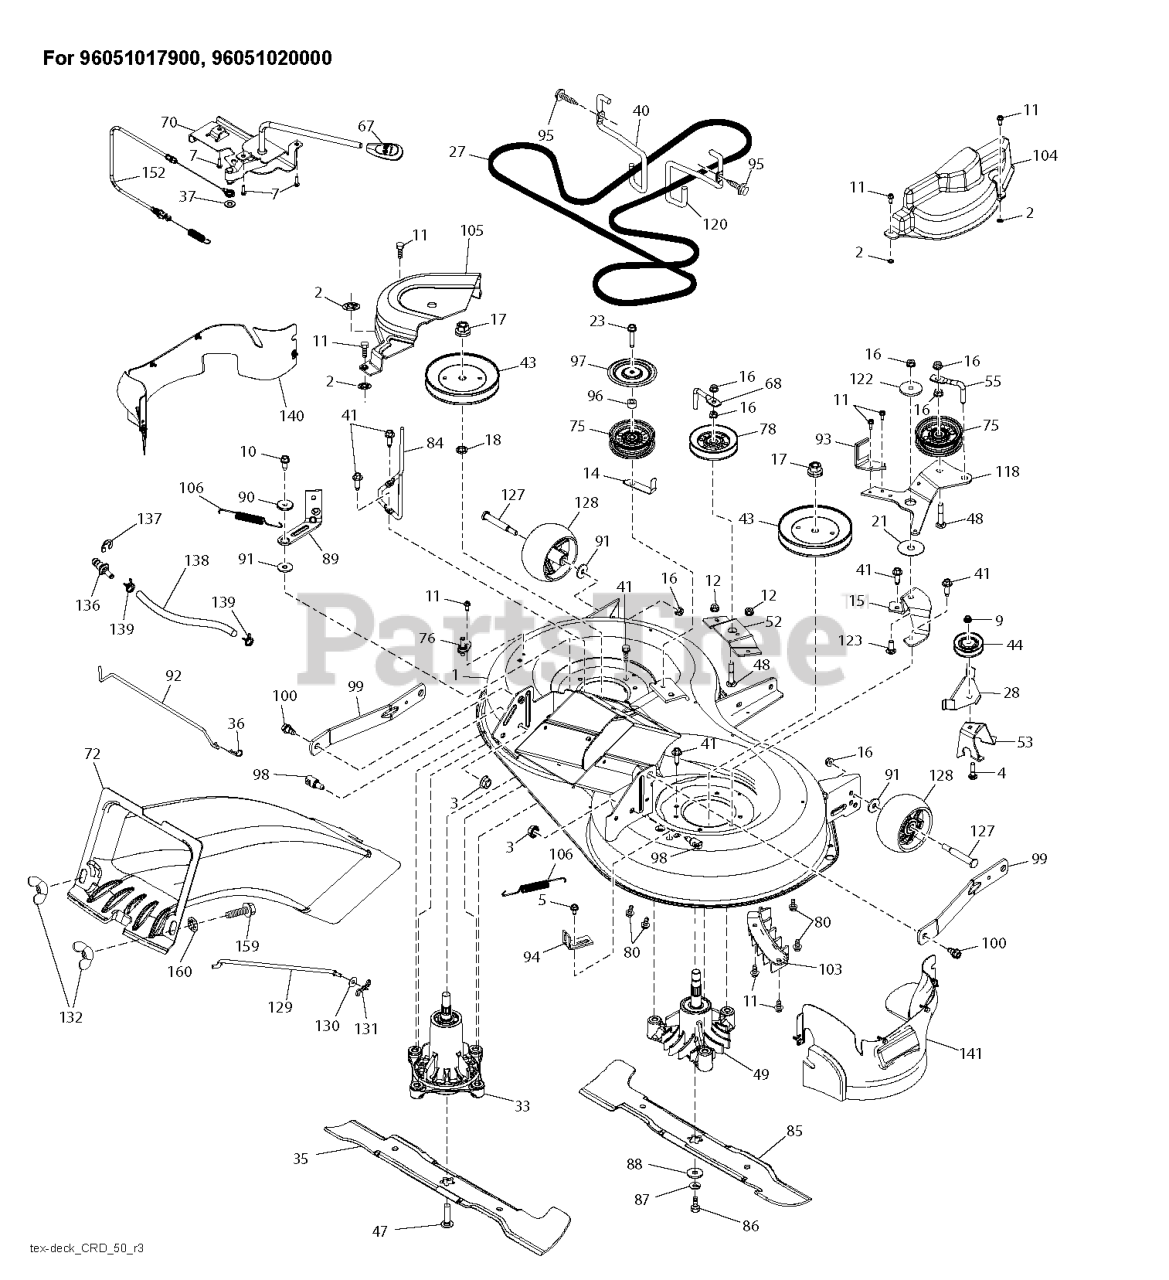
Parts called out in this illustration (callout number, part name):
1	KIT.SVC.DECK.WLD.97CM.TEX.498
2	PALNUT 1/4
4	BOLT.CARRIAGE.5/16-18
5	BOLT.5/16HEX.WHS.HD
9	NUT HEXAGON FLANGE 5/16-18 ST
10	SCREW 3/8-16X1
11	SCREW.1/4-20X5/8
12	NUT HEXAGON FLANGE 5/16-18 ST
14	KEEPER, BELT IDLER
15	BRACKET CRD IDLER ARM MOUNT BL
16	NUT LOCK FLG 3/8-16 UNC
18	WASHER.SPACER.MANDREL
23	BOLT;HEX_3/8-16 X 1.78.CLRZINC
27	Belts
27	BELT CRD DECK DRIVE
28	KEEPER 97 CRD ANGLED IDLER KEE
33	KIT.MANDREL.NONGREASE.TALL
35	BLADE.3N1.LH.CRD.97
36	RETAINER M
37	WASHER PLAIN WASHER 3/8 X 0.08
40	KEEPER BELT ENGINE LH
41	BOLT.HEX.WASHR.HED.313-18X1.19
43	PULLEY.MANDREL.5.438.PD
44	PULLEY.V-IDLER.
47	SCREW.SEMS.7/16-20X1.HEX.HEAD
49	KIT.MANDREL.3 POINT
53	BRACKET 97 CRD ANGLED V-IDLER
67	HANDLE.CLUTCH.CABLE.LT
70	CLUTCH.ASM.MANUAL.LT.PRED
72	CHUTE.TEX.CRD.GEN I.97 UPPER
76	1/2" BARB.DECK.WASHOUT.PORT
78	REPL BY 532 1467-63
80	GSPW Bolts
84	KEEPER.BLT.PNT.MNDRL.PULL.6.25
85	BLADE.3N1.RH.CRD.97
86	BOLT.3/8-24X1.25GR8. LHTHRD
88	WASHER.BLADE
89	ARM.BRAKE.97.LH
90	SPACER.RETAINER
92	LINK 97 CRD MANUAL DRIVE BRAKE
93	BRAKE CRD RH BRAKE ARM BLACK E
94	BRKT.CLUTCH.CABLE
95	SCREW, 3/8-16X3/4
96	SPACER
97	PROTECTOR
98	STUD.W/"D"ANTI-ROTATION
99	ARM.SUSPENSION.MOWER.R
100	BOLT.SHOULDER
103	GUARD GUARD FRONT VENT
104	GUARD 97CRD RH MANDREL COVER;
105	MANDREL MANDREL COVER LH
106	SPRING.BRAKE.RETURN.38"
120	KEEPER BELT RH
122	SPACER.RETAINER.MOWER
128	WHEEL.GAUGE.RALLY
129	ROD.ANTI.SWAY.48/54"K4
131	PIN.COTTER.5/16.BOW TI
132	KNOB.HANDLE.3/8.TRI-POINT.BLAC
136	PLUG WASHOUT PORT HOOKUP
138	HOSE.3/8ID.BULK.12"
140	GUARD.ASM.LH.CRD.FRENCH.97CM
140	GUARD.ASSEMBLY.97.LH.FRENCH
141	GUARD.ASSEMBLY.97.RH.FRENCH
141	GUARD.ASM.RH.CRD.FR.97CM.SLOT
152	CABLE CABLE CLUTCH MANUAL W/S
